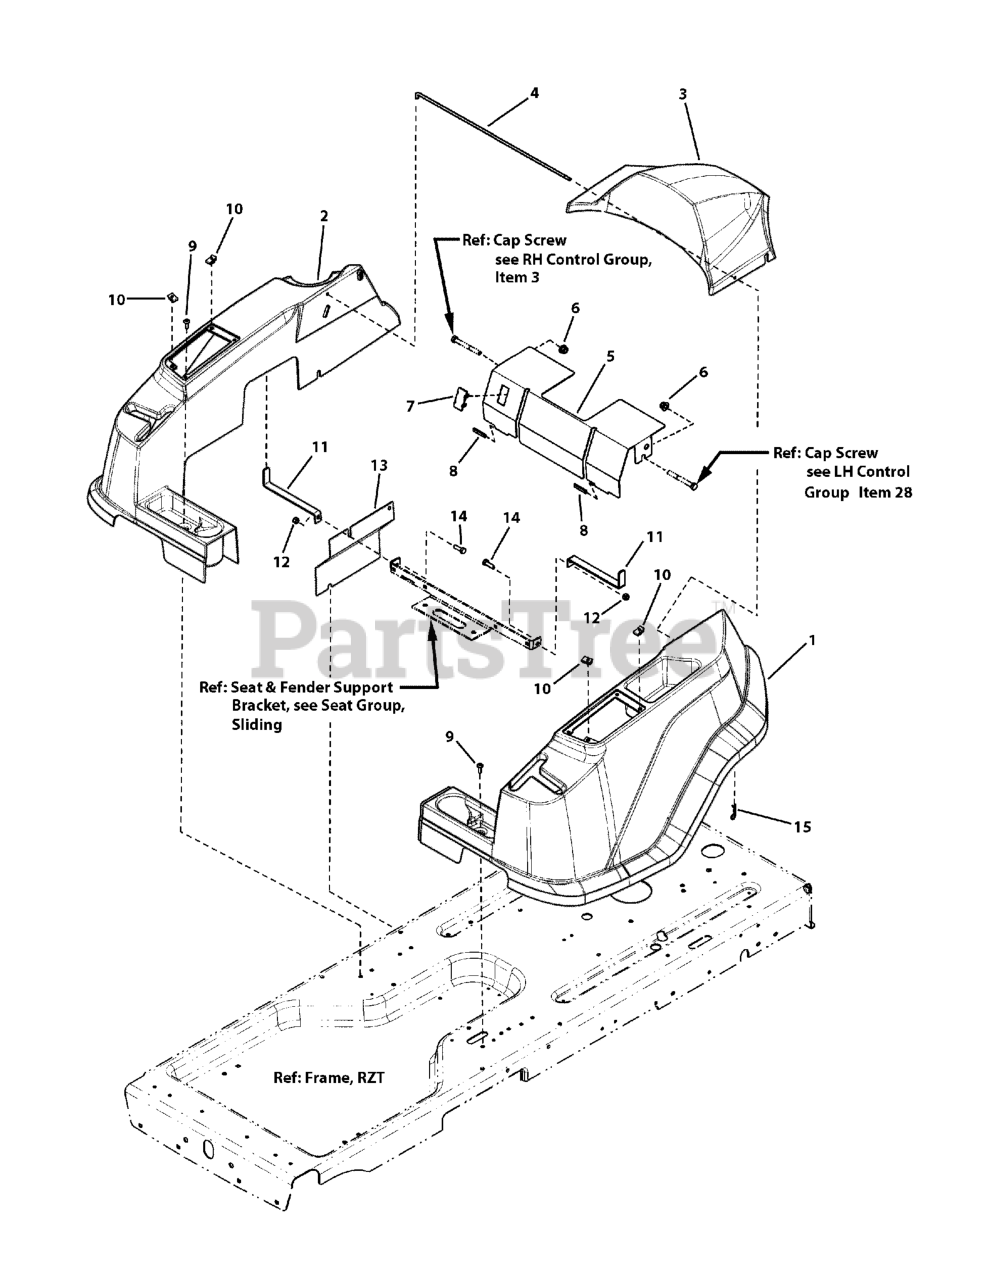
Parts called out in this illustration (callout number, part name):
1	FENDER, LH
2	FENDER, RH
3	COVER, Engine
4	ROD, Pivot, Hood
5	COVER, BATTERY, 285z
6	NUT, Hex Flange ESNA, 3/8-16
7	PLUG, Hole
8	STRIP, TRIM
9	SCREW, 1/4-20 x 3/4, Pan Head Torx
10	U-NUT, 1/4-20
11	BRACKET, Support, Fender
12	NUT, 5/16-18 3B Nyloc, YZ
13	PLATE, Side, RH
14	SCREW, 5/16-18 x 1" Hex Head Cap, GR 5, YZ
15	HAIR PIN, 3/32 x 1-1/2", YZ
